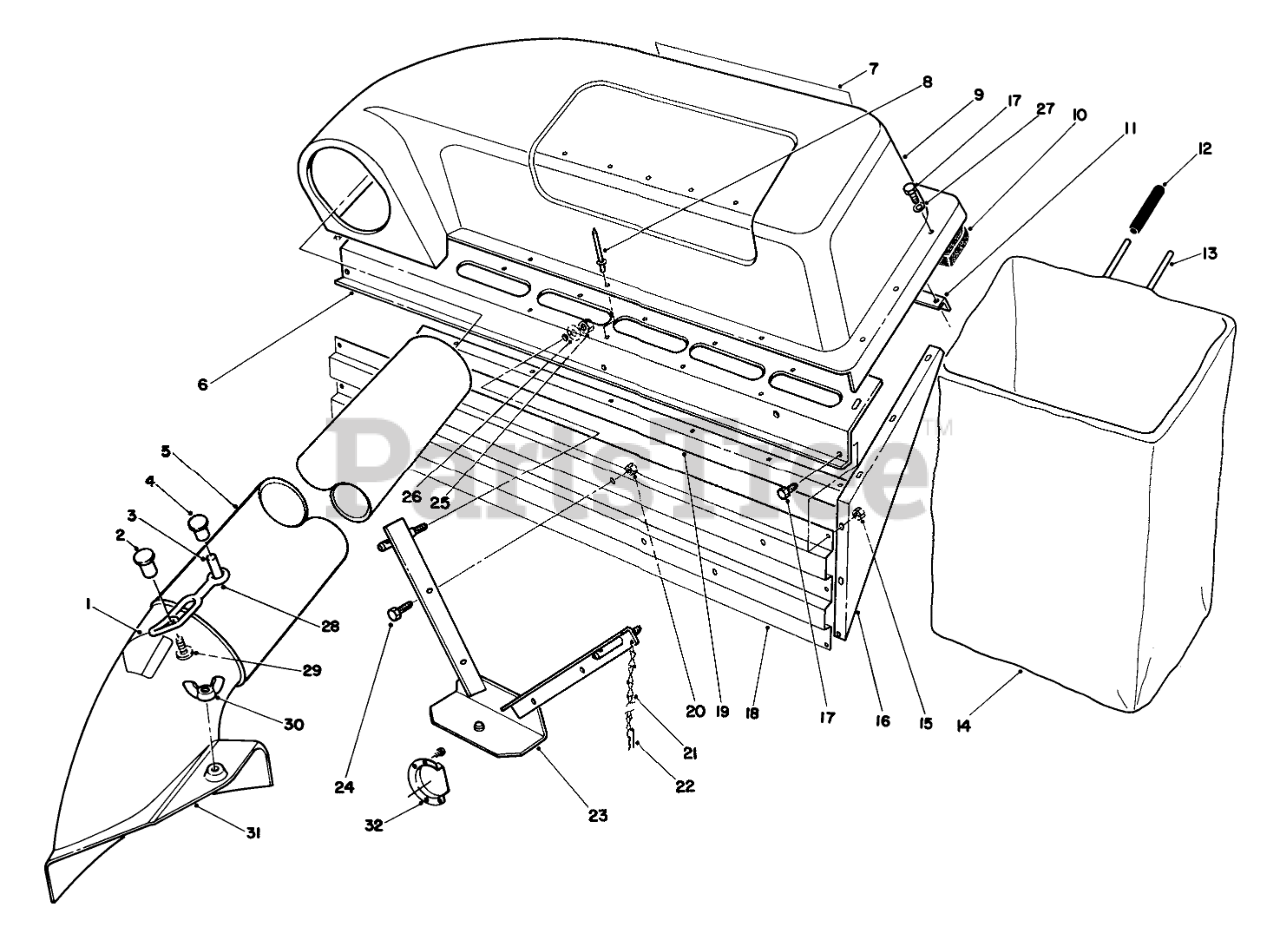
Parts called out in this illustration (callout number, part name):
1	DECAL-DANGER
3	SPACER-INTERLOCK
4	FASTENER-PANEL
6	COVER SUPT BAFFLE B
7	Decal-Twin Bagger
8	RIVET-POP
9	COVER
10	FOAM SEAL
11	BAG FRAME BRKT
12	GRIP-HANDLE, BAG
13	BAG FRAME
15	NUT-LOCK, NI
16	Plate-Side
17	SCREW-HH
18	COVER
19	BAG SUPPORT CHANNEL
20	NUT-LOCK, NI
21	6-LINK CHAIN W/HOOK
22	PIN-HAIR
23	V-Bracket
24	SCREW-HH
25	NUT-LOCK, NI
26	WASHER-FLAT
27	WASHER-FLAT
28	RETAINER-DUCT
29	Screw
30	NUT-WING SPECL
31	Assembly-Chute (Incl. Ref. #1, 4 & 29)
32	MUFFLER DEFLECTOR
